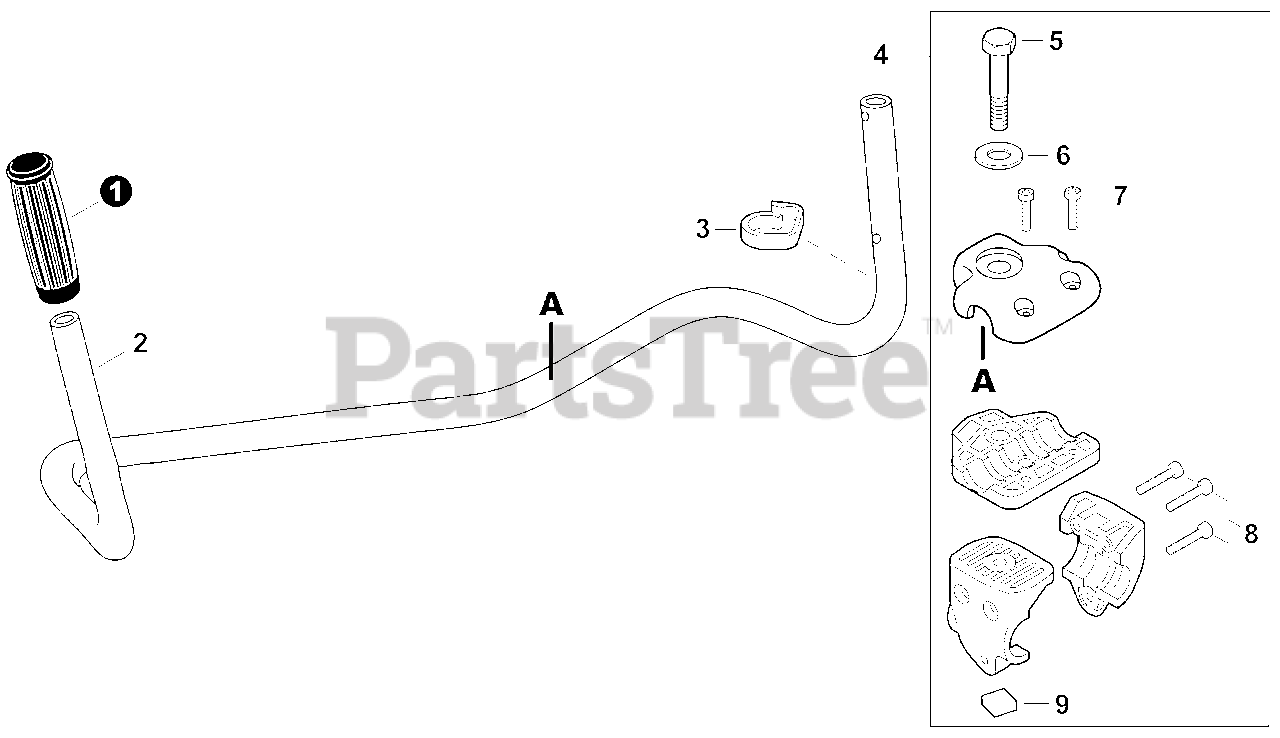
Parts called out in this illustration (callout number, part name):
1	GRIP, HANDLE
2	HANDLEBAR
4	BRACKET KIT, HANDLEBAR
5	BOLT 8×55
6	WASHER 8
7	BOLT, TORX 5×20
8	BOLT, TORX 5×25
9	NUT 8×1.25
